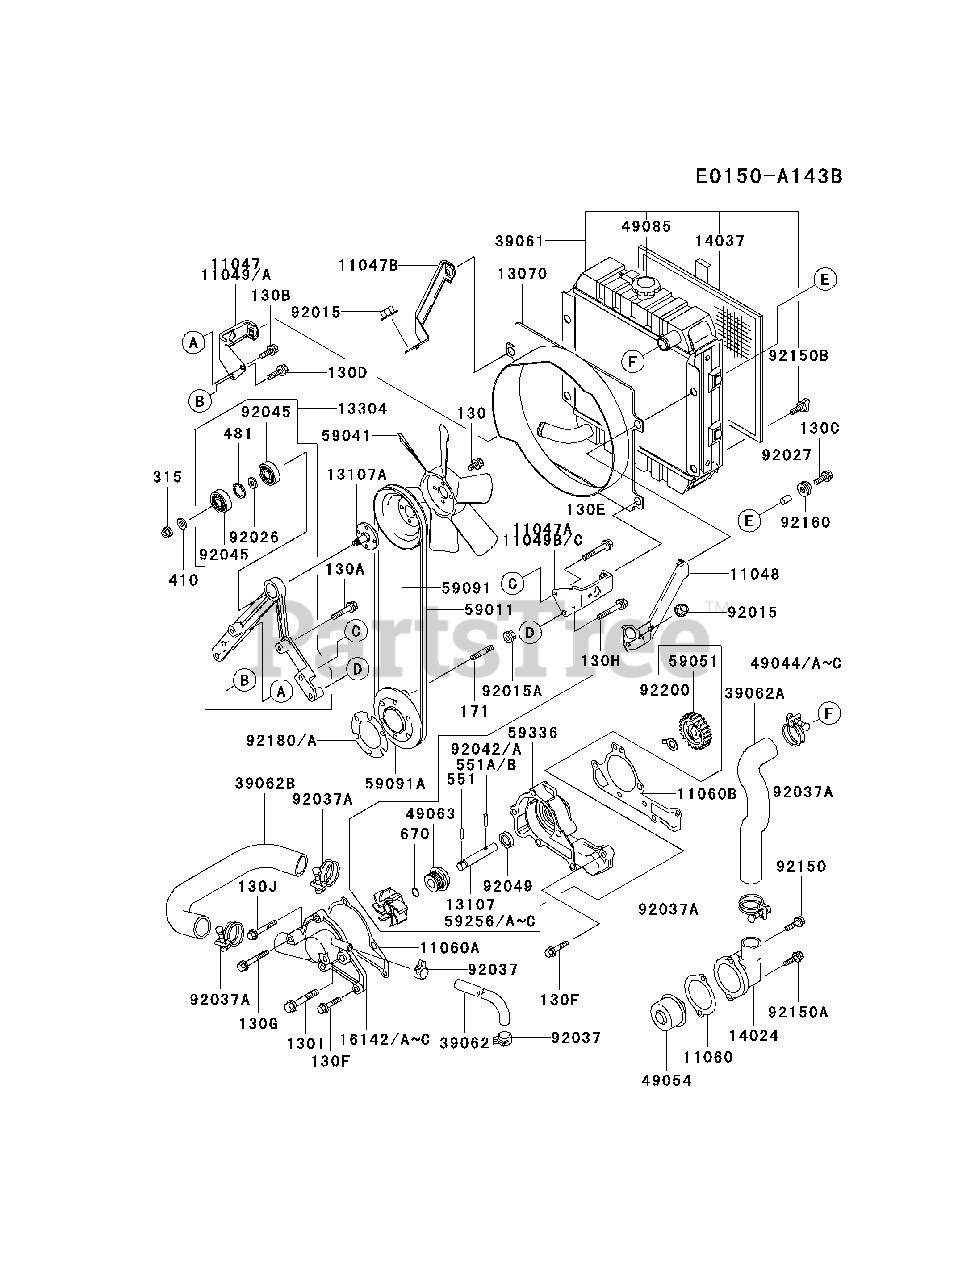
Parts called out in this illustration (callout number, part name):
130J	BOLT-FLANGED
171	BOLT-STUD
315	NUT-HEX-FINE
410	W-PLAIN-S
481	CIRCLIP
551	PIN-DOWEL
551A	PIN-DOWEL
670	O RING
